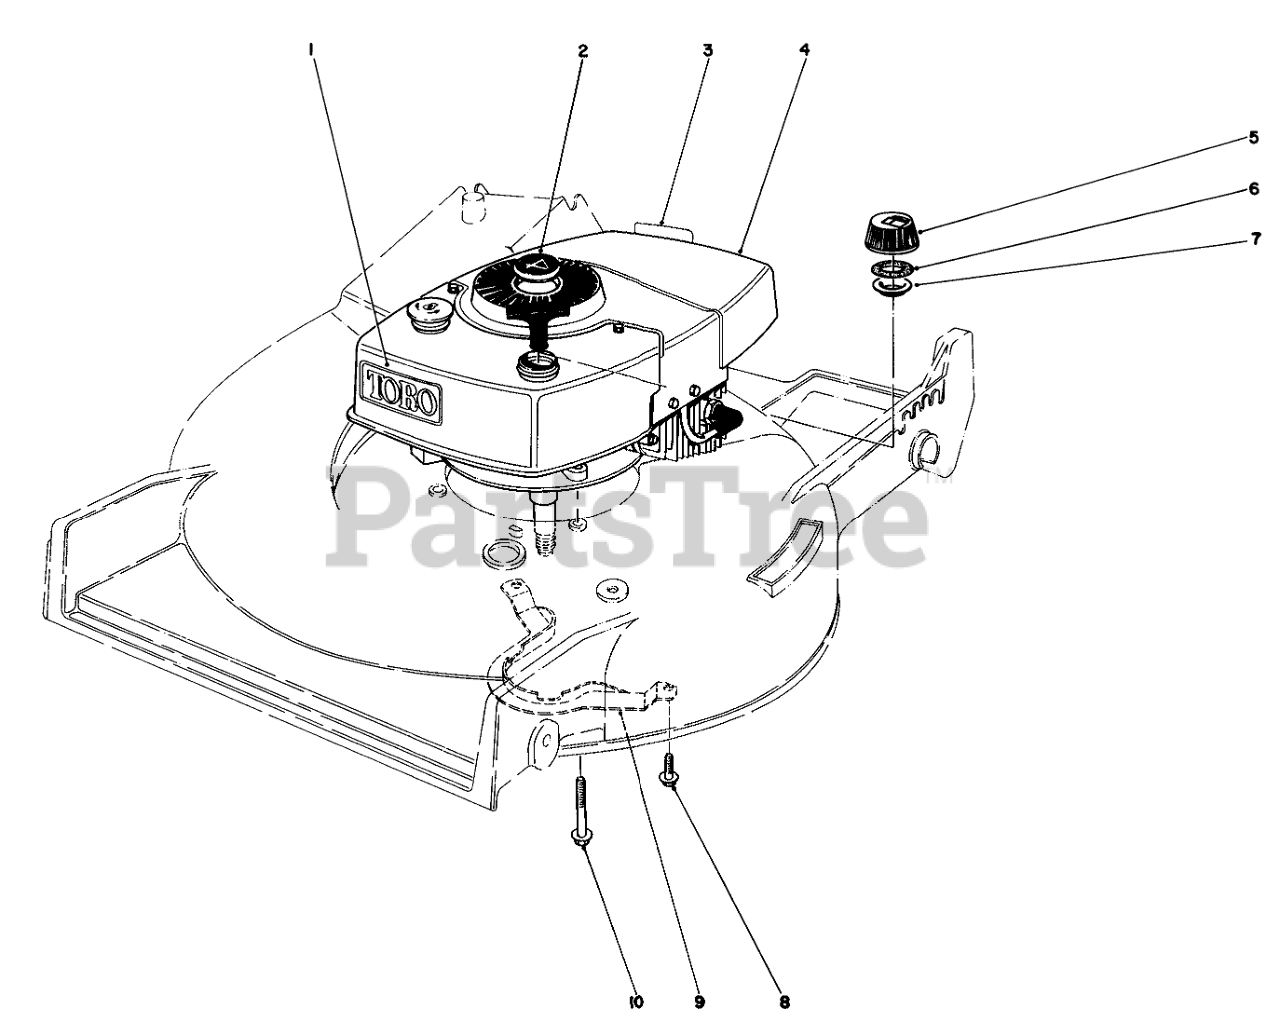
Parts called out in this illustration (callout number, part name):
1	Decal Tow
2	PLUG BUTTON
3	Decal-Maintenan
4	Engine
5	Gas Cap Assembly (Incl. Ref. #6 & 7)
6	GASKET
7	GAS CAP BAFFLE
8	Screw
9	BELT GUIDE
10	3/8-16 X 2 CAPSCREW
